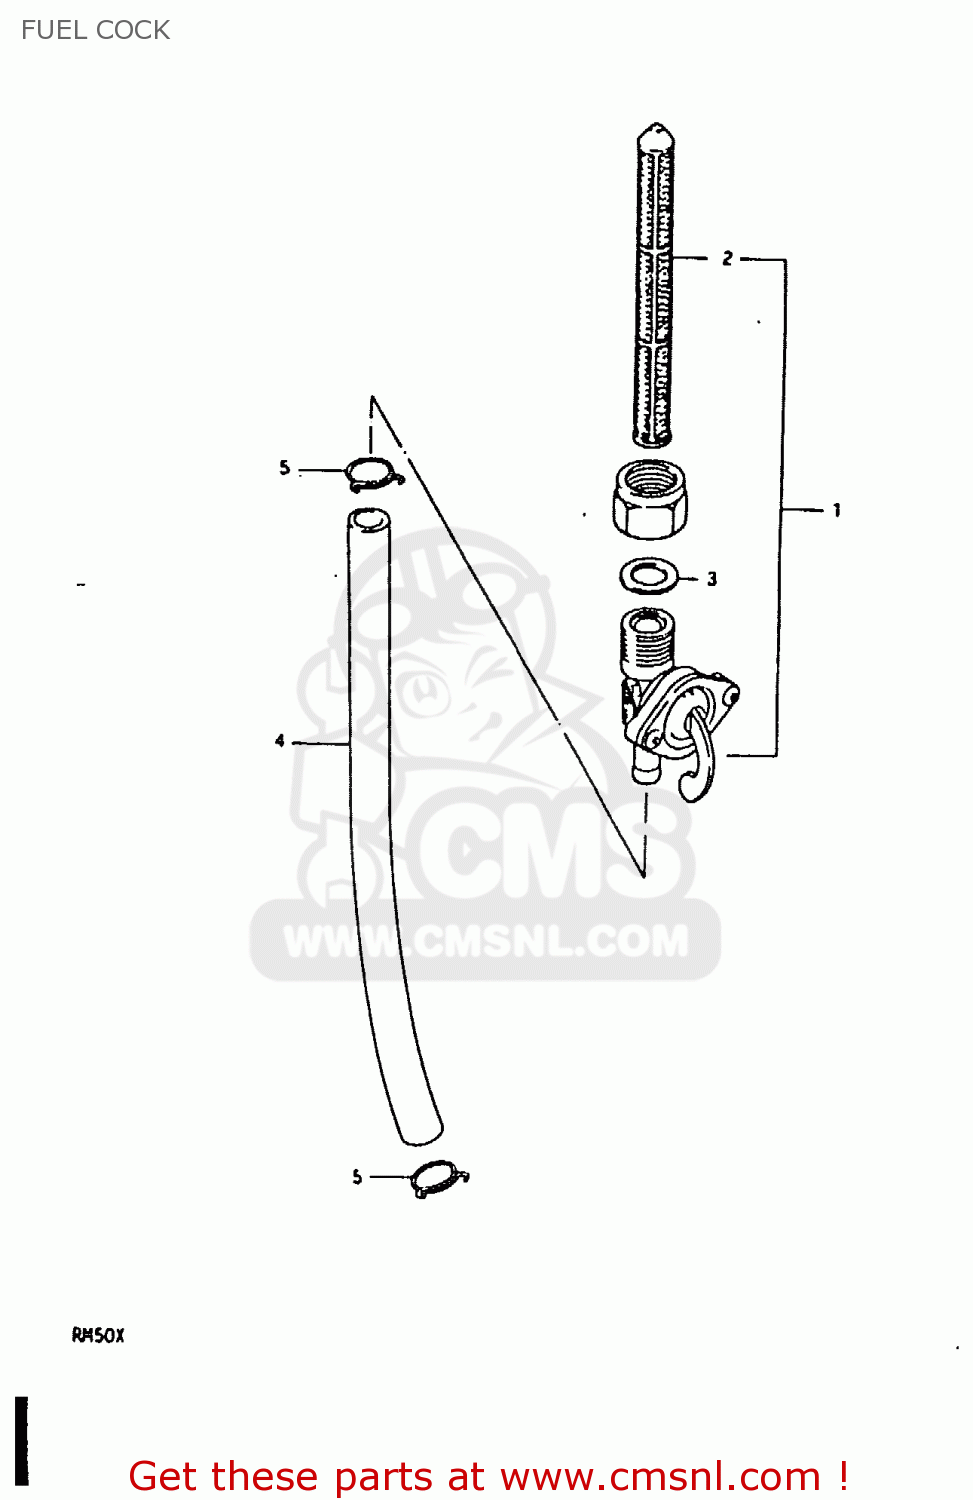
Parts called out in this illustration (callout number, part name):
1	COCK ASSY,FUEL
2	FILTER,FUEL
3	GASKET,FUEL COCK (NAS)
4	HOSE
5	CLIP
